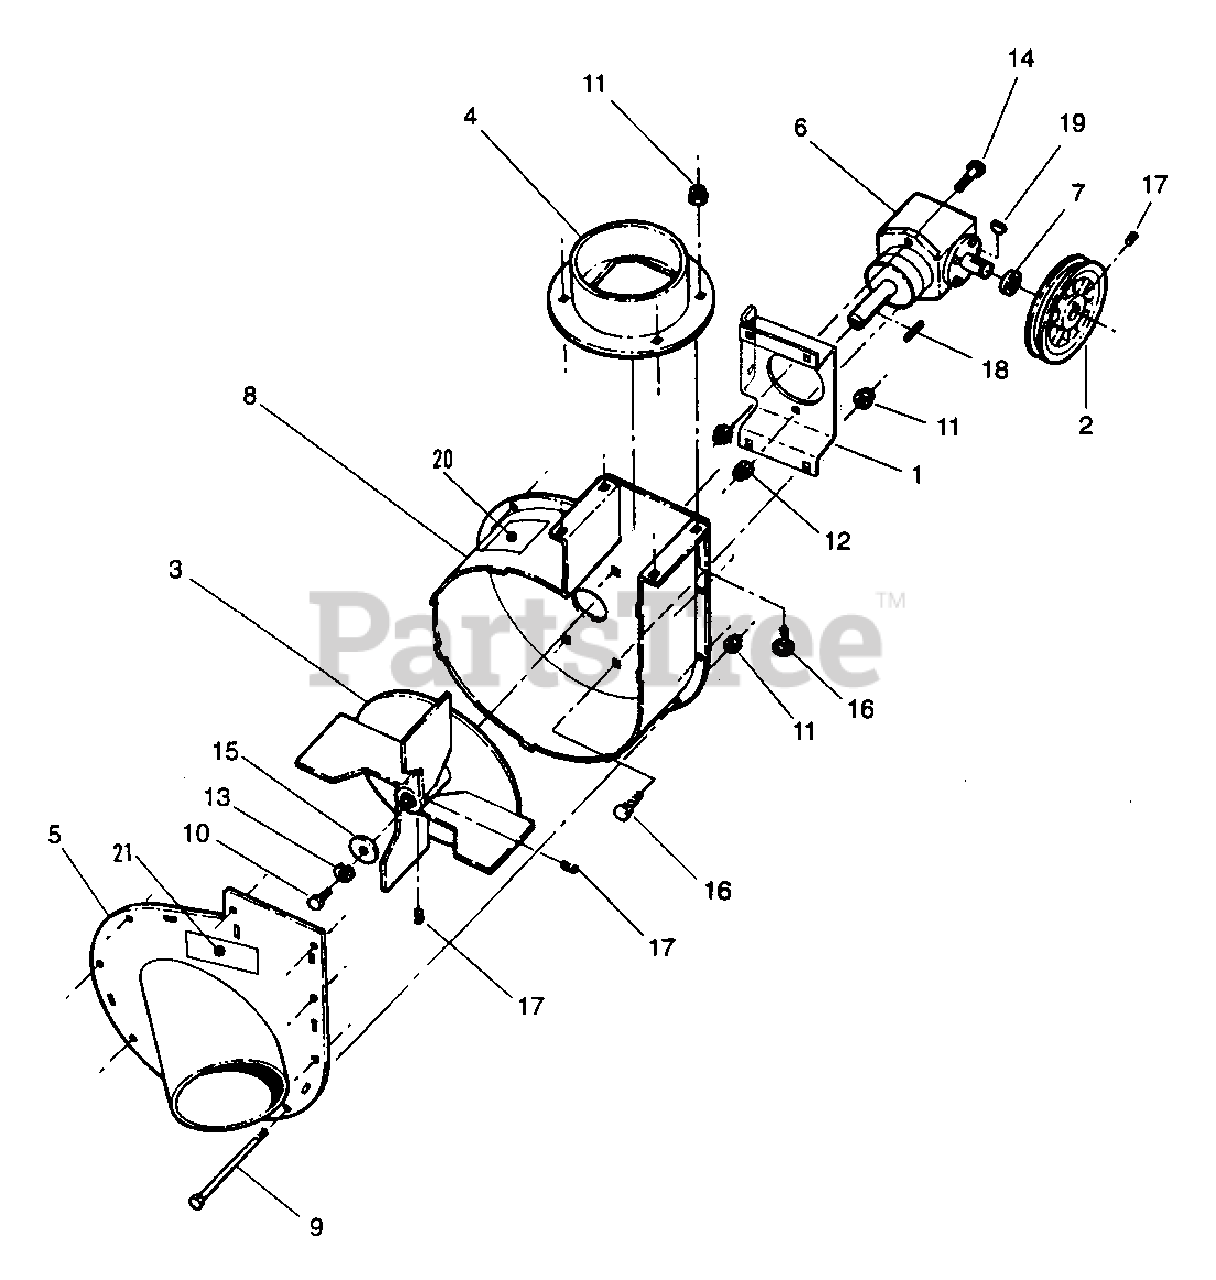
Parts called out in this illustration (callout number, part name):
1	MOUNT, Grass Catcher Gearbox, MMZ/OFZ
2	PULLEY, 5.45 O.D. Cast
3	WELDMENT, Blower Impeller
4	WELDMENT, Chute Adapter
5	WELDMENT, Impeller Housing Front
6	GEARBOX, Right Angle
7	SPACER, Gearbox, Grass Catcher Pulley
8	WELDMENT, Blower Housing
9	SCREW, 3/8-16 x 5-1/2" Hex Head Cap, Grade 5
10	SCREW, 3/8-24 x 1" Hex Head Cap, Grade 5
11	NUT, 5/16-18 HEX NYLON LOCK
12	NUT, 3/8-16 HEX NYLON LOCK
13	WASHER, 3/8" SPLIT LOCK
14	BOLT, 3/8-16 X 1-1/4" GD5 CZ
15	WASHER, 13/32" x 1-1/2" Flat
16	BOLT, 5/16-18 x 3/4" Short Neck Carriage, Grade 5
17	SCREW, 5/16 x 5/8" Hex Socket Head Set
18	KEY, 3/16 x 1-1/2" Square
19	KEY, 5/32 x 5/8" Woodruff
20	DECAL, Danger Hand
21	DECAL, Caution
